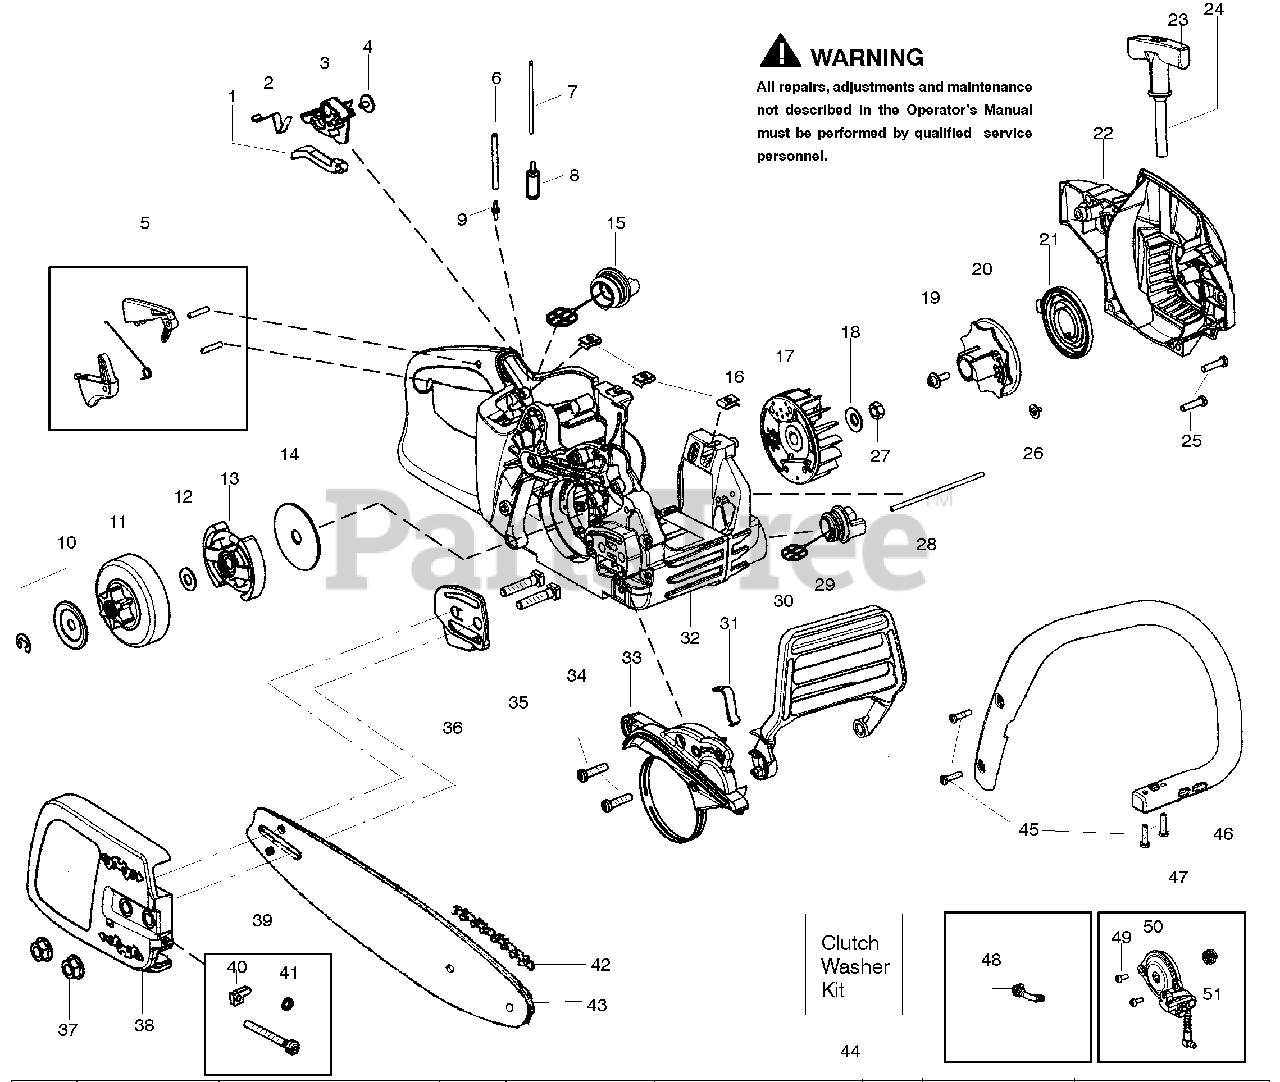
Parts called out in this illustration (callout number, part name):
1	Knob-Choke
2	Spring-Ign. Switch
3	Lever-Ign. Switch
5	Kit-Trigger/Lockout
6	Kit-Fuel Line (Large)
7	Kit-Fuel Line (Small)
8	Assy-Fuel Pick Up
9	Fitting-Fuel line
10	Kit-Clutch Washer
11	Assy-Clutch Drum 3/8"
12	Kit-Clutch Washer
13	Assy-Clutch
14	Washer-Large Clutch
15	Assy-Fuel Cap w/ret
16	Nut-"U" type speed
17	Assy-Flywheel
18	Washer-Flywheel
20	Pulley - Starter
21	Spring -Starter
22	Housing-Fan
23	Handle-Starter
24	Kit-Rope
27	Nut-Flywheel
28	Assy-Oil Vent
29	Assy-Oil Cap w/ret.
30	Handguard
31	Spring-Handguard
32	Assy-Chassis
33	Kit-Chainbrake
35	Bolt-Bar
36	Plate-Bar
38	Assy-Clutch Cover
39	Kit-Bar Adjust
40	Pin-Bar Adjust
41	Retainer-Bar Adjust
42	16" Chain
43	16" Bar
44	Kit-Clutch Washer
46	Handle-Front
47	Kit-Oil Pump
48	Assy-Oil Pick Up
50	Assy-Oil Pump
51	Gear-Worm
